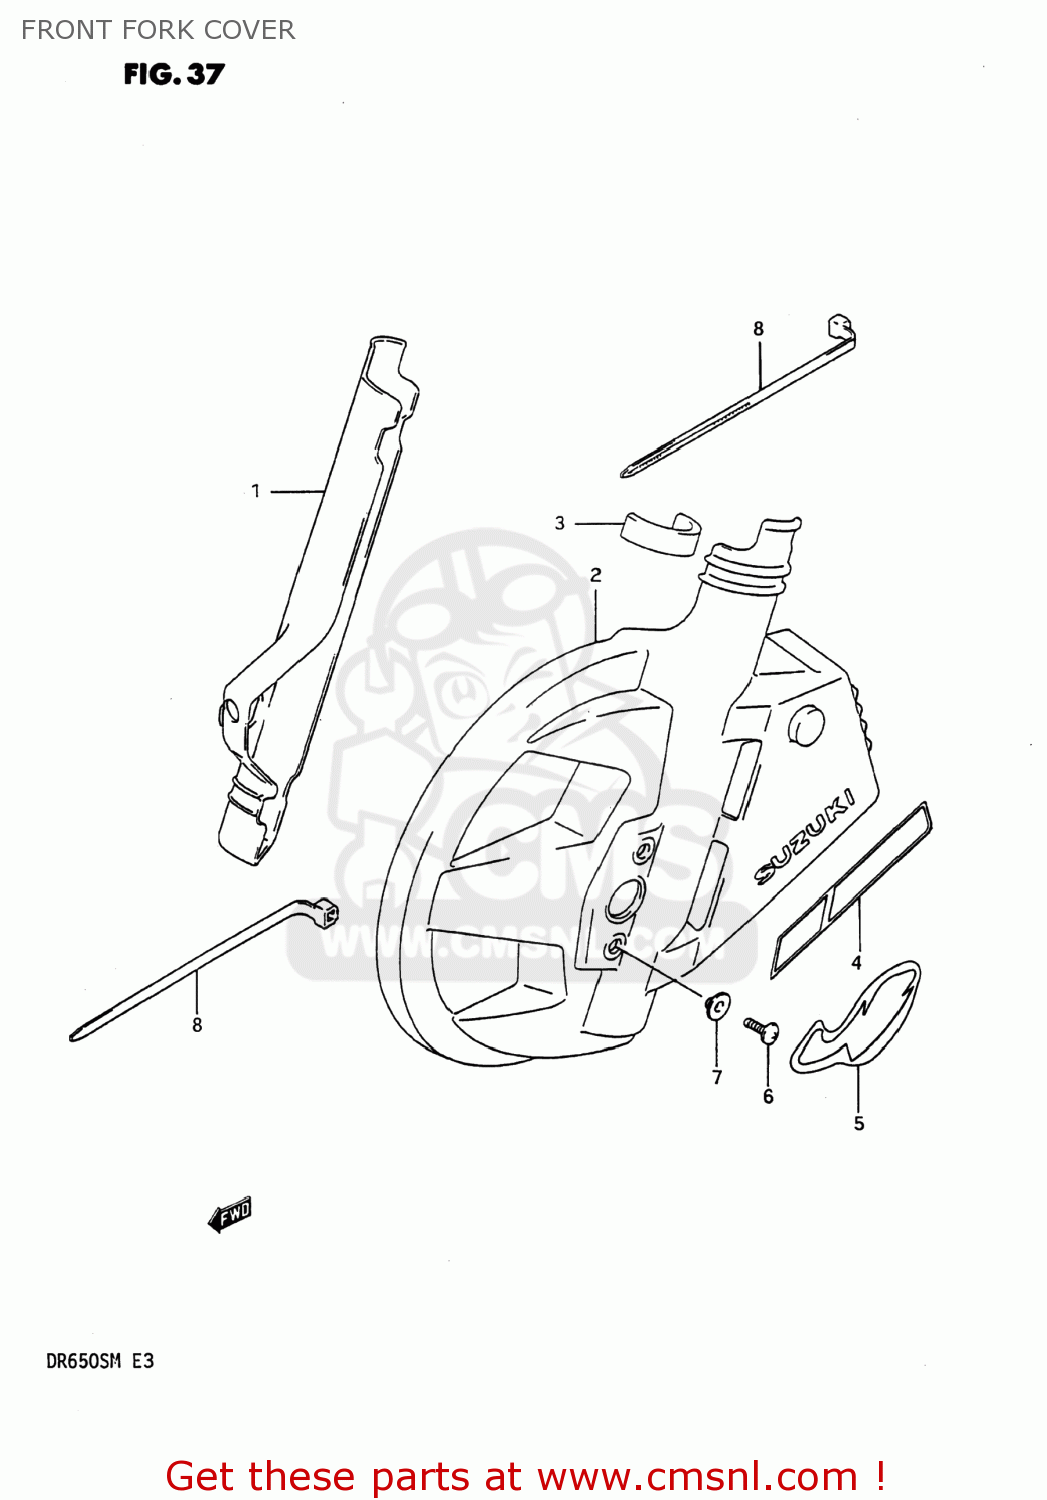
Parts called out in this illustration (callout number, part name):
1	PROTECTOR,FRONT FORK,RIGHT
2	PROTECTOR,FRONT FORK,LEFT
3	CUSHION
5	TAPE,DISC COVER BRAKE
6	SCREW 6X12
7	WASHER
8	CLAMP
